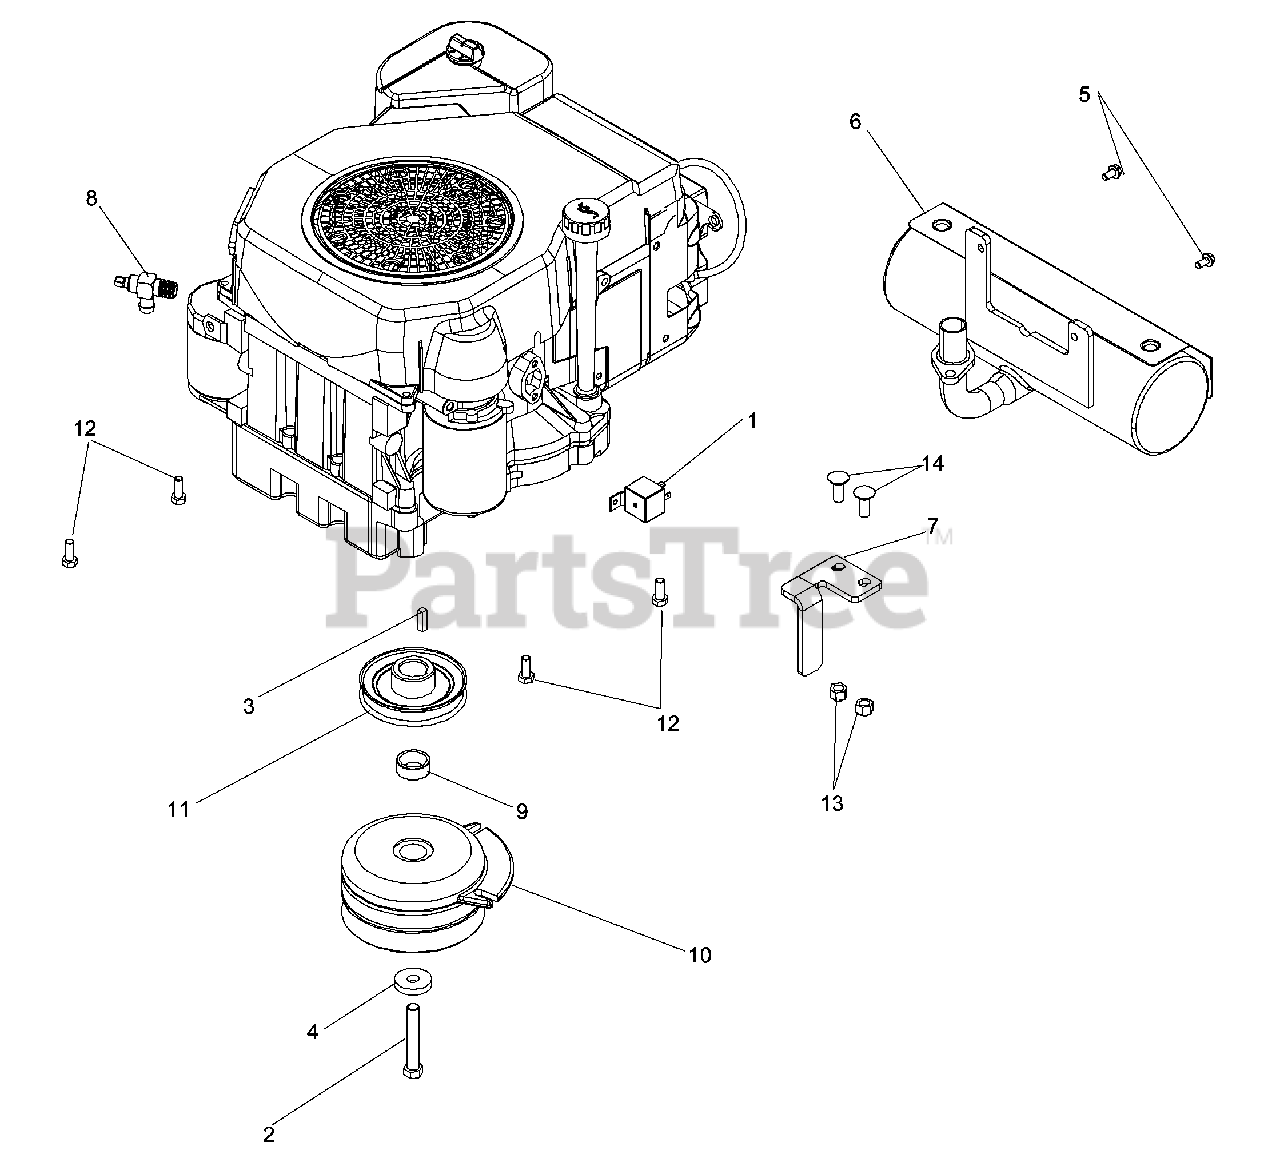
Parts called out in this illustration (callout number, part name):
2	HCS 7/16-20 X 2-3/4
3	KEY - 1/4 X .88
4	WASHER .43X1.38X.25
5	1/4-20 X 1/2 HWH FORM SCR H
6	MUFFLER
7	ANCHOR CLUTCH
8	OIL DRAIN
9	HUB BEARING SPACER
11	DRIVE PULLEY-ENGINE
13	NUT 3/8-16 NYLOC
14	RHSNB 3/8C X 1
